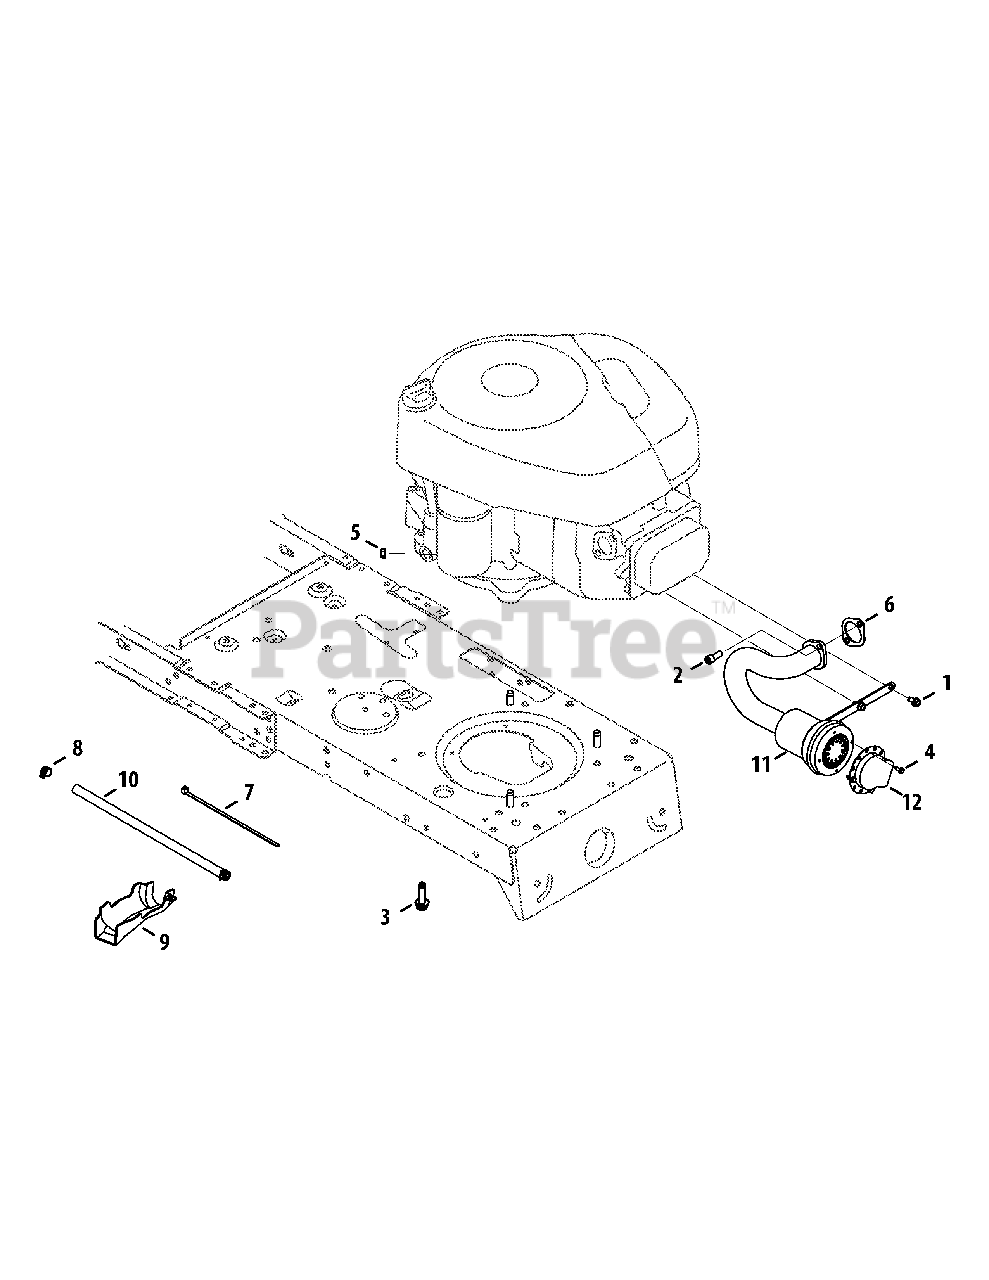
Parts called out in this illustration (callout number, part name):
1	Screw, ab, #8-18, 0.500
2	Tap Screw, 3/8-16, 1.000
3	Tap Screw, 1/4-20, 0.500
4	Screw, Socket Head, 5/16-18, .750
5	Sems Nut, 1/4-20
6	Exhaust Gasket
7	Cable Tie, 3/16 X .05 X 7.4
8	Hose Clamp, .490 Dia.
9	Oil Drain Sleeve
10	Hose, fuel, low Permeation, 1/4
11	Muffler
12	Muffler Deflector
